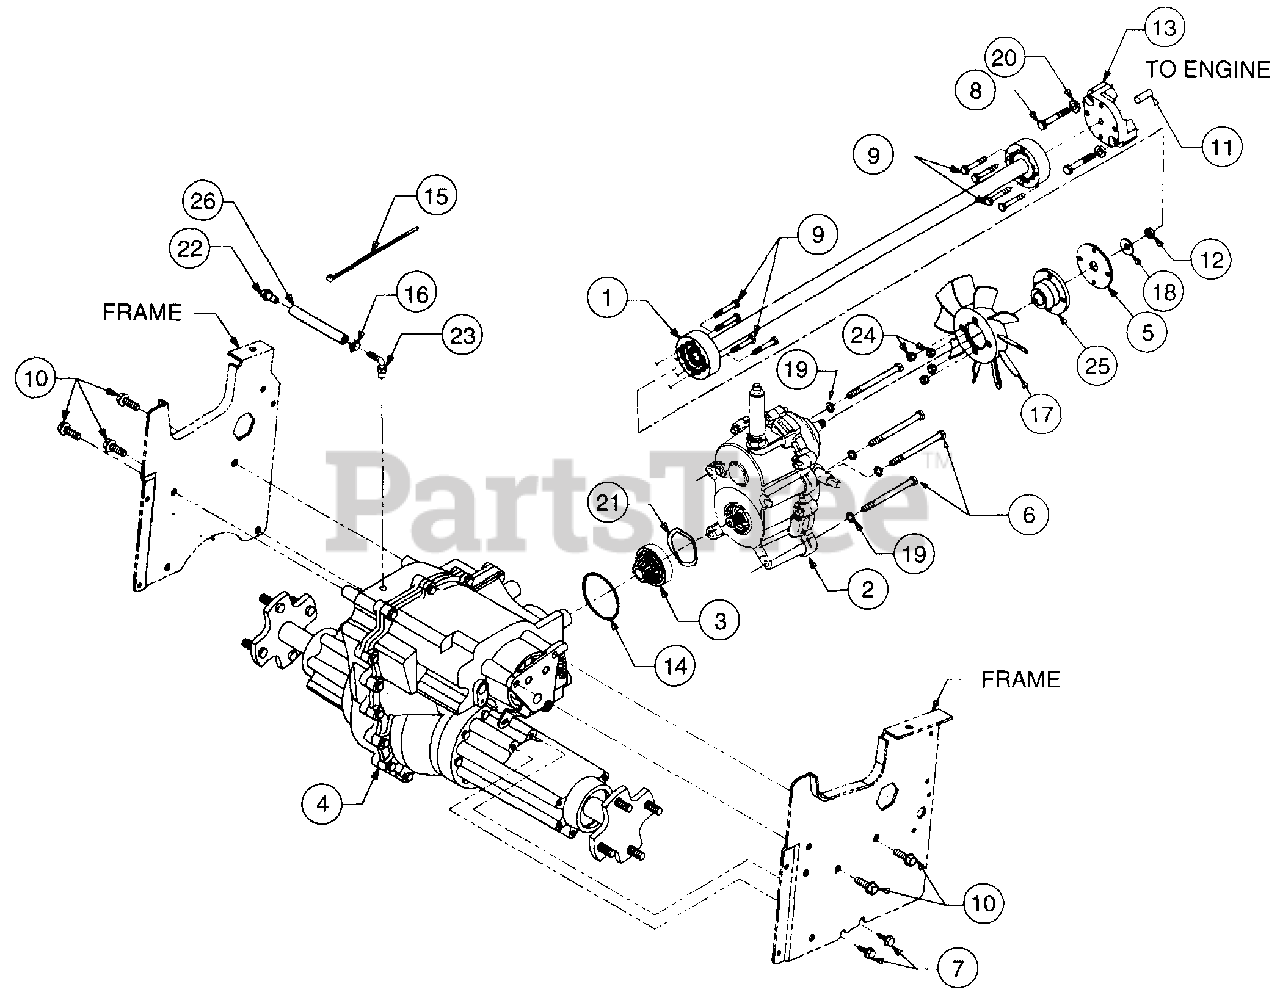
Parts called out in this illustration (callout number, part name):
1	Shaft Assy, Drive, 29.06 Lg
2	Clutch Assembly
3	Pinion Assy, Input
4	Transmission Assy, 6-Speed
5	Plate, Drive Shaft Spacer
6	Screw, Hex Cap, 5/16-18 x 4.0 GR5
7	Screw, Hex Wash Hd Tapp 5/16-18 x .75
8	Screw, Hex Cap, 5/16-18 x 1.75 GR5
9	Screw, Hex Patch, 1/4-20 x 1.62 GR5
10	Screw, Hex Wash Hd Tapp 3/8-16 x 1.25
11	Pin, Locating
12	Nut, Hex Center Lock Jam, 3/8-24
13	Adapter, Drive Shaft
14	O-Ring, 2.75 x .103
15	Tie, Self-Clinch Cable
16	Clamp, Hose
17	Fan, 10 Blade Cooling
18	Washer, Bell, .380 x .88 x .063
19	Washer, Lock, 5/16
20	Washer, Flat, .312 x .750 x .119
21	Washer, Spring Wave, 1.96 x 2.44 x .06
23	Fitting, Elbow
24	Nut, Fan, 1/4-20
25	Adapter, Clutch
26	Line, Fuel, 7 in. Lg
